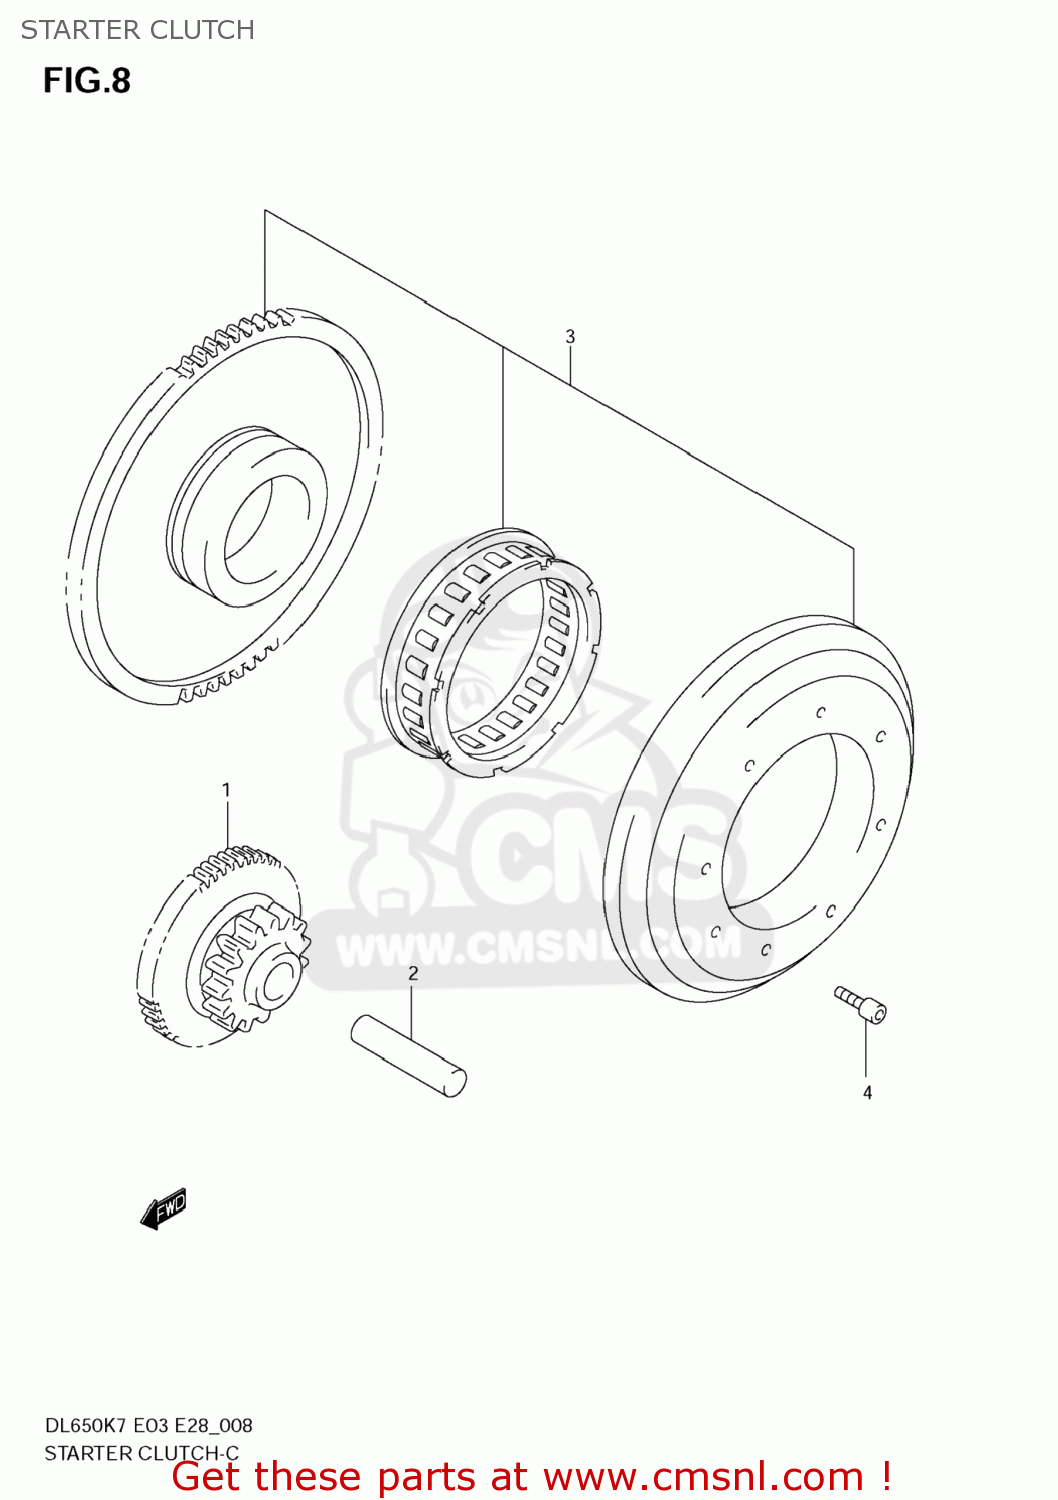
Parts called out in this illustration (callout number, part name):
1	GEAR,STARTER IDLE
2	PIN(8X12X45.5)
3	CLUTCH SET,STARTER
4	BOLT(8X16)
